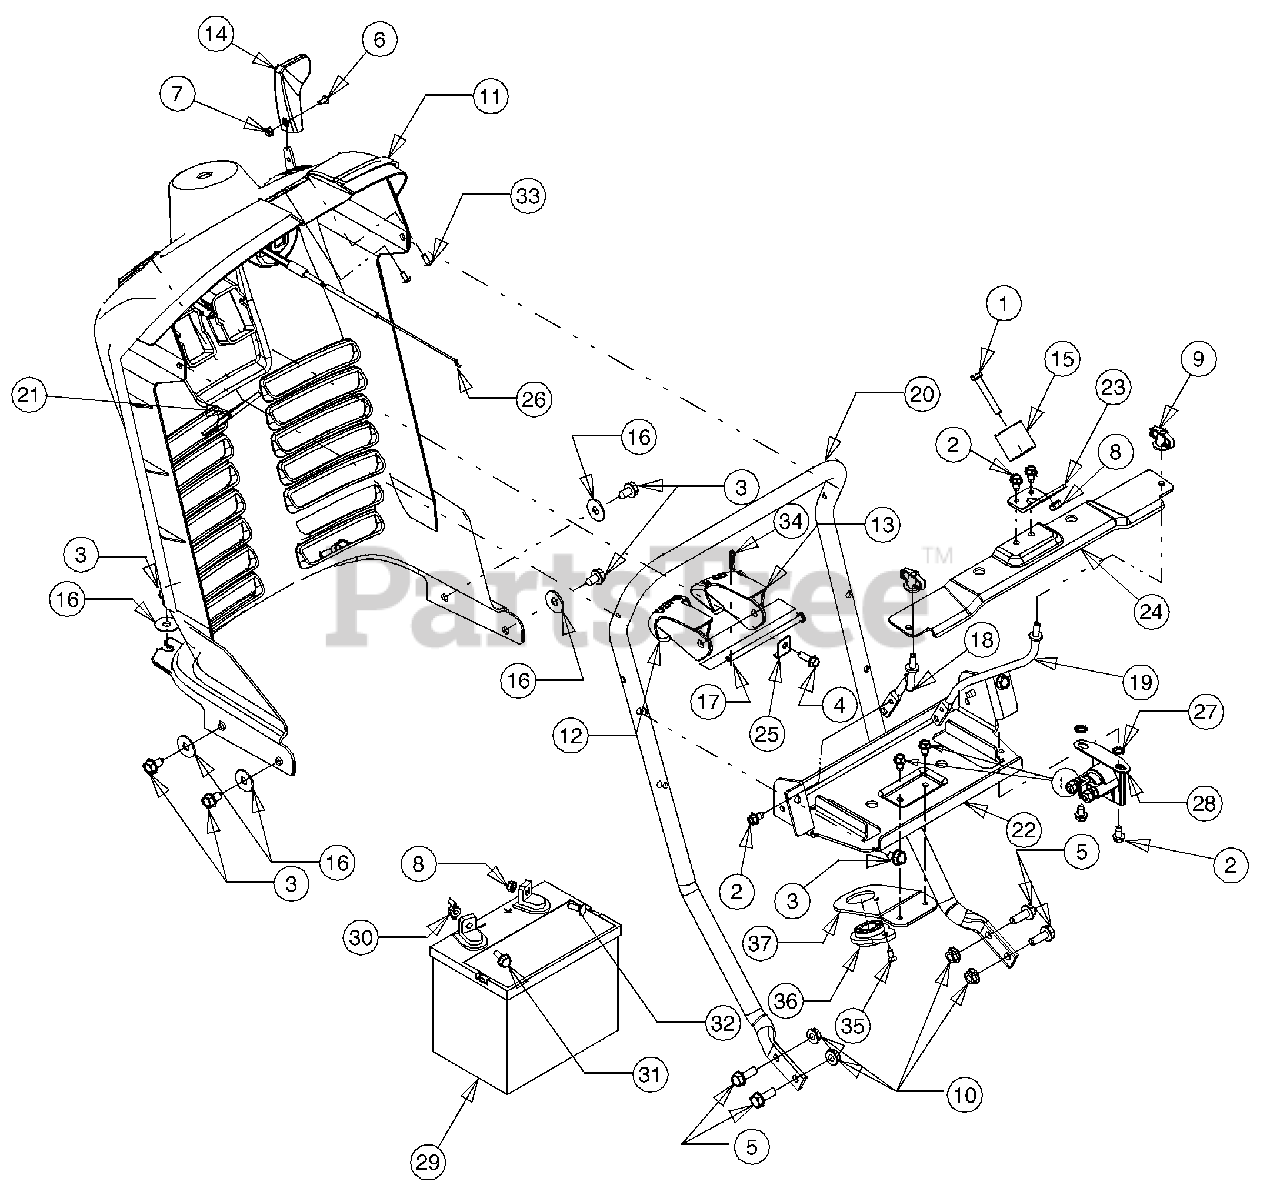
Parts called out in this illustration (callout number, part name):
1	Screw, 1/4-20, 1.75, Gr5
2	Screw, Self-tapping, 1/4-20, 0.500
3	Screw, 5/16-18, 0.625
4	Screw, 1/4-15, 0.750
5	Screw, 5/16-18, .875, Gr5
6	Screw, Machine, #8-32, 0.375, Trus Phillips
7	Nut, 8-32
8	Nut, Hex, 1/4-20, Sems
9	Nut, Wing, 1/4-20 w/ Bell Washer
10	Nut, Flange Lock, 5/16-18, Gr5
12	Lever, Dash, Cruise
13	Lever, Dash, Brake
14	Knob, Throttle Control
15	Roller, Latch, Hood
16	Washer, Flat, .349 x 1.00 x .063
17	Rod, .250 Dia x 4.25 Lg.
18	Rod, Support, Side Panel RH
19	Rod, Support, Side Panel LH
26	Control, Choke, 23 Lg.
27	Washer, External Lock, 1/4
28	Solenoid, 12V, 100 Amp
29	Battery, 270 CCA, Wet
30	Nut, Wing, 1/4-20
31	Screw, Shoulder, 1/4-20, .25 x .15
32	Screw, 1/4-20, .620, Gr5
33	Screw, #10-24 X .375
34	Internal Cotter Pin, .072 x 1.13
35	Screw, Oval Countersunk, #10-16 X .625
36	Bearing, Steering Column, .634 ID x 1.36
37	Steering Bracket
